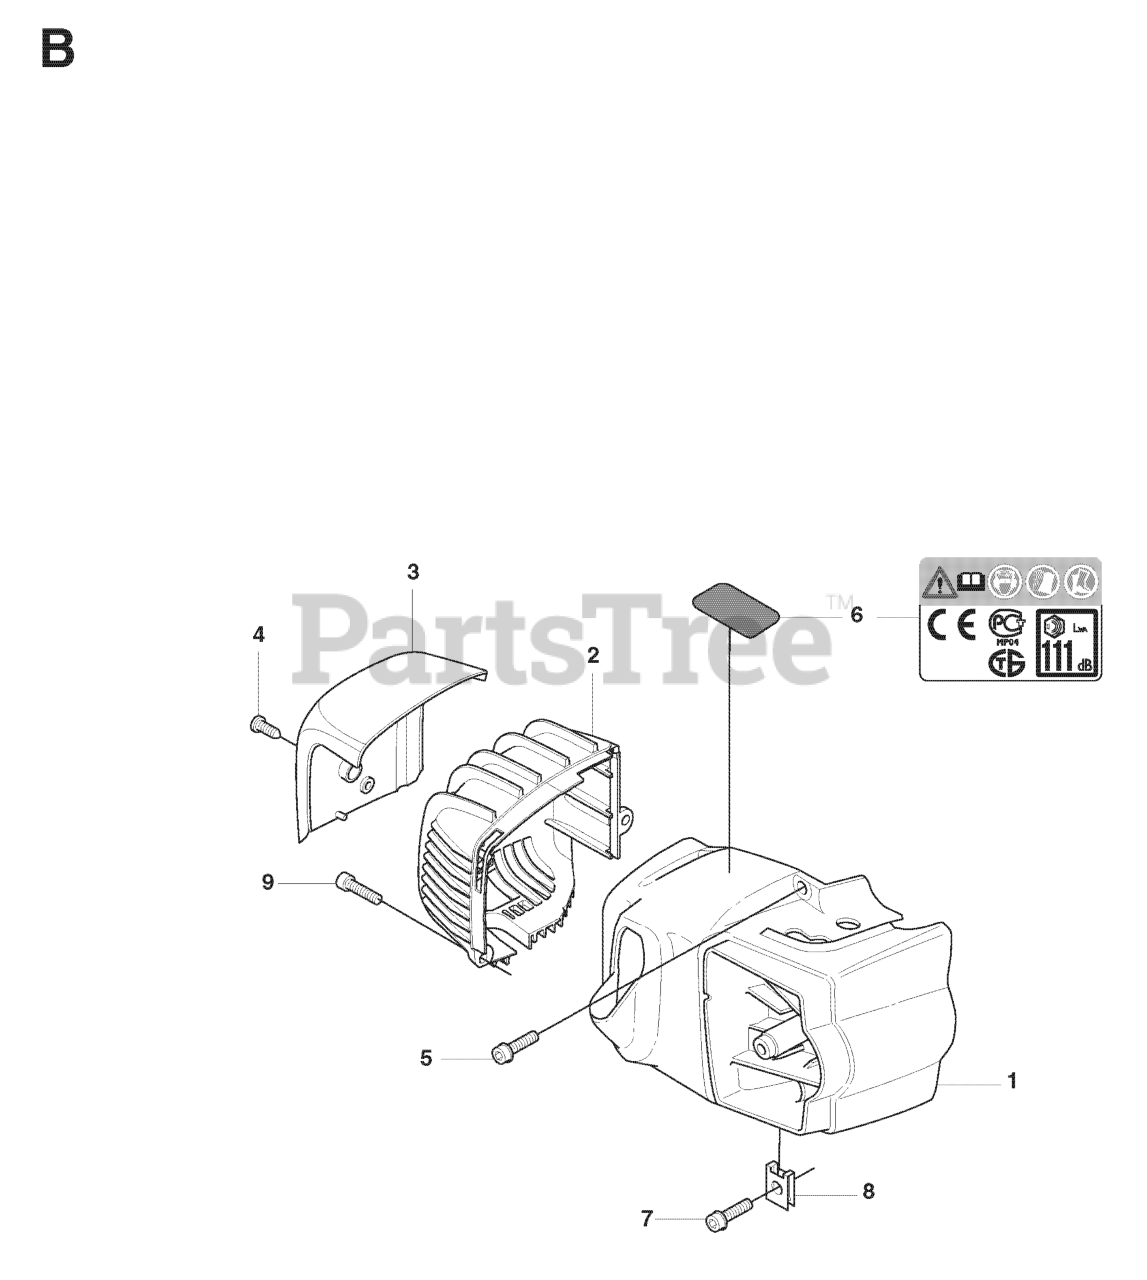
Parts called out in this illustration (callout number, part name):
2	RP MUFFLER COVER
3	MUFFLER SHIELD
6	LABEL WARNING CE
9	SCREW W/ LOCKING FLUID
